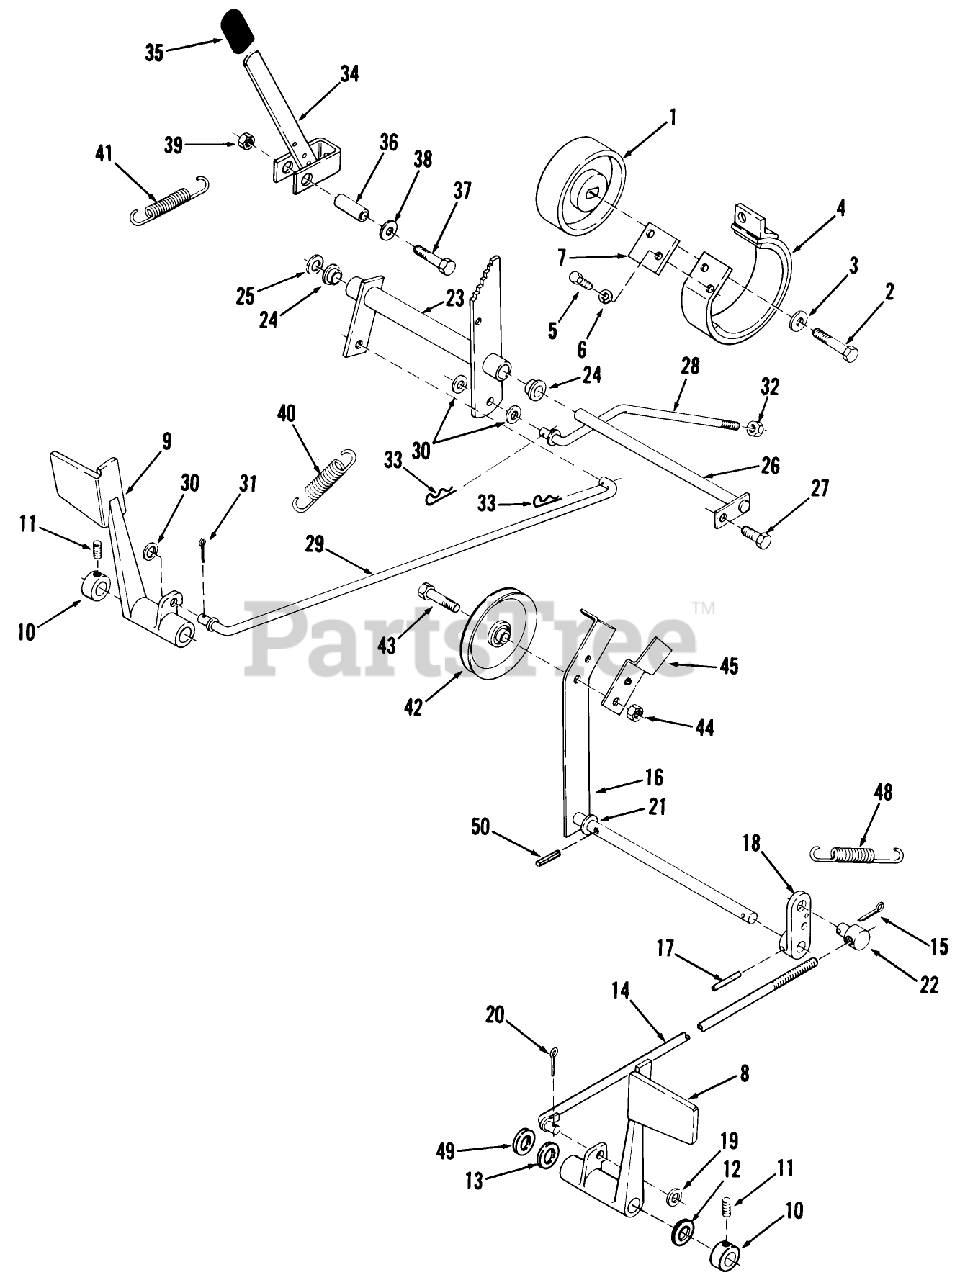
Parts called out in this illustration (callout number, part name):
1	PEDAL R
2	BUSHING
3	Collar
4	SCREW-SET
5	Spacer
6	SPRING
7	ASY BRAK RD WAR
9	NUT
10	Washer
11	SPRING-COMPRESSION
13	DRUM-BRAKE
14	WASHER -4
15	BOLT
16	BOLT
17	ASSY-BRAKE BAND
18	Brake Pivot Arm
19	BUSHING-BRAKE PIVOT
20	BOLT
21	Nut
22	Washer
23	Washer
24	Cotter Pin
